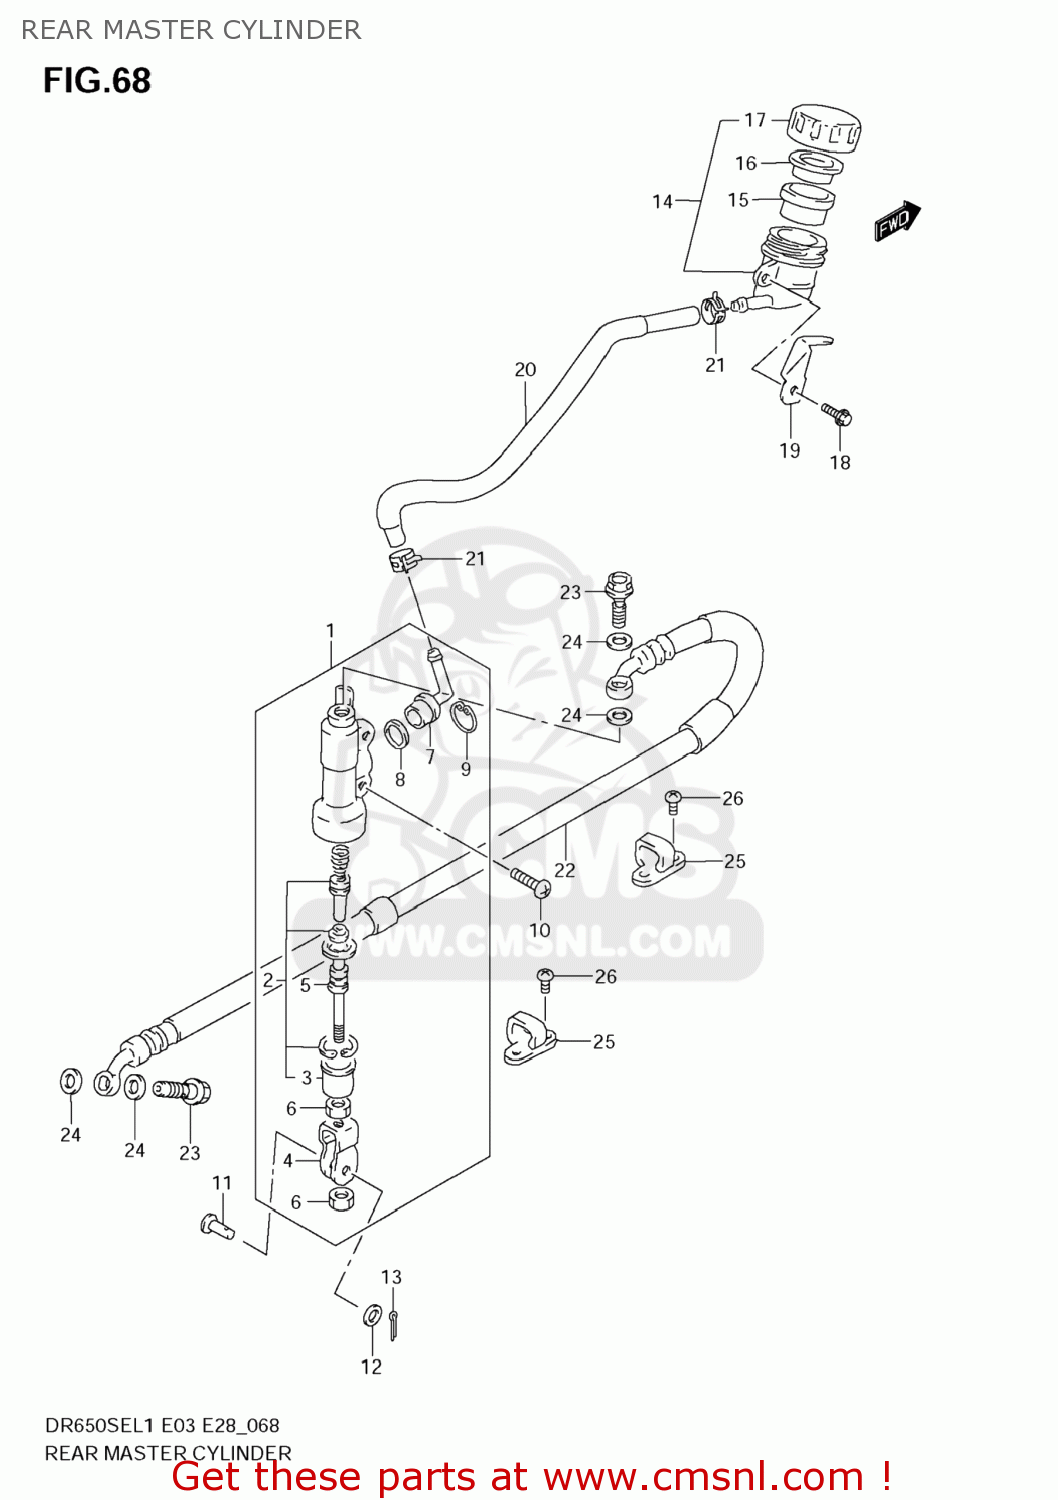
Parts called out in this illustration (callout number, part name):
1	CYLINDER ASSY,RR MASTER
2	PISTON/CUP SET
3	BOOT
4	YOKE
5	ROD,PUSH
6	NUT
7	CONNECTOR
8	O RING
9	CIRCLIP
10	SCREW(6X16)
11	PIN(8X20)
12	WASHER(8.5X14X1.6)
13	PIN
14	TANK ASSY,RR BRAKE RESERVOIR
15	DIAPHRAGM
16	PLATE
17	CAP
18	BOLT
19	GUARD,RSVR TANK CAP
20	HOSE,RESERVOIR TANK
21	CLIP
22	HOSE,RR BRAKE
23	BOLT UNION
24	WASHER(10X15X1.5)
25	GUIDE,RR BRAKE
26	SCREW
